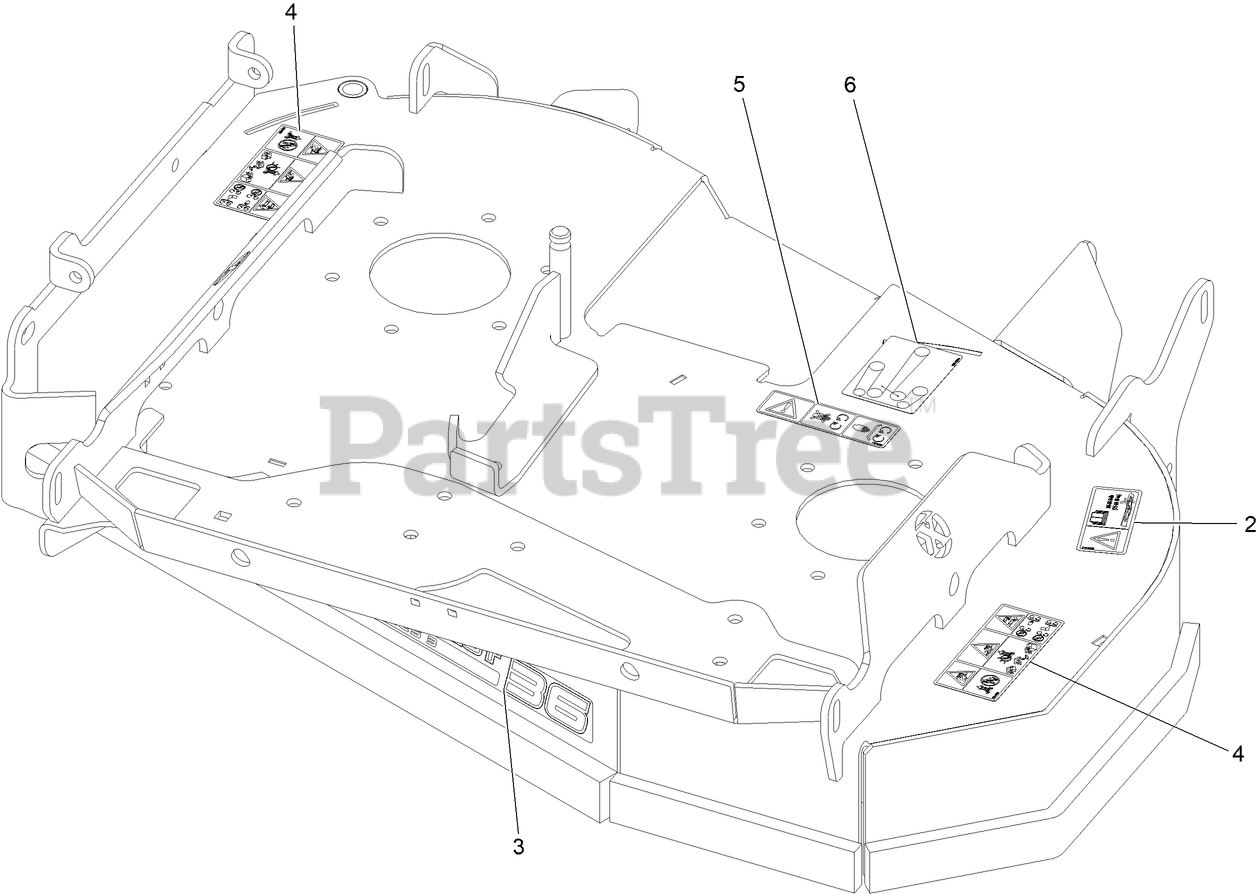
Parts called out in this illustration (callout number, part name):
2	DECAL-TORQUE, BOLT
3	DECAL-ULTRACUT 36 SERIES 3
4	DECAL-WARNING THROWN OBJECT
5	DECAL-COVER, MISSING
6	DECAL-BELT ROUTING
